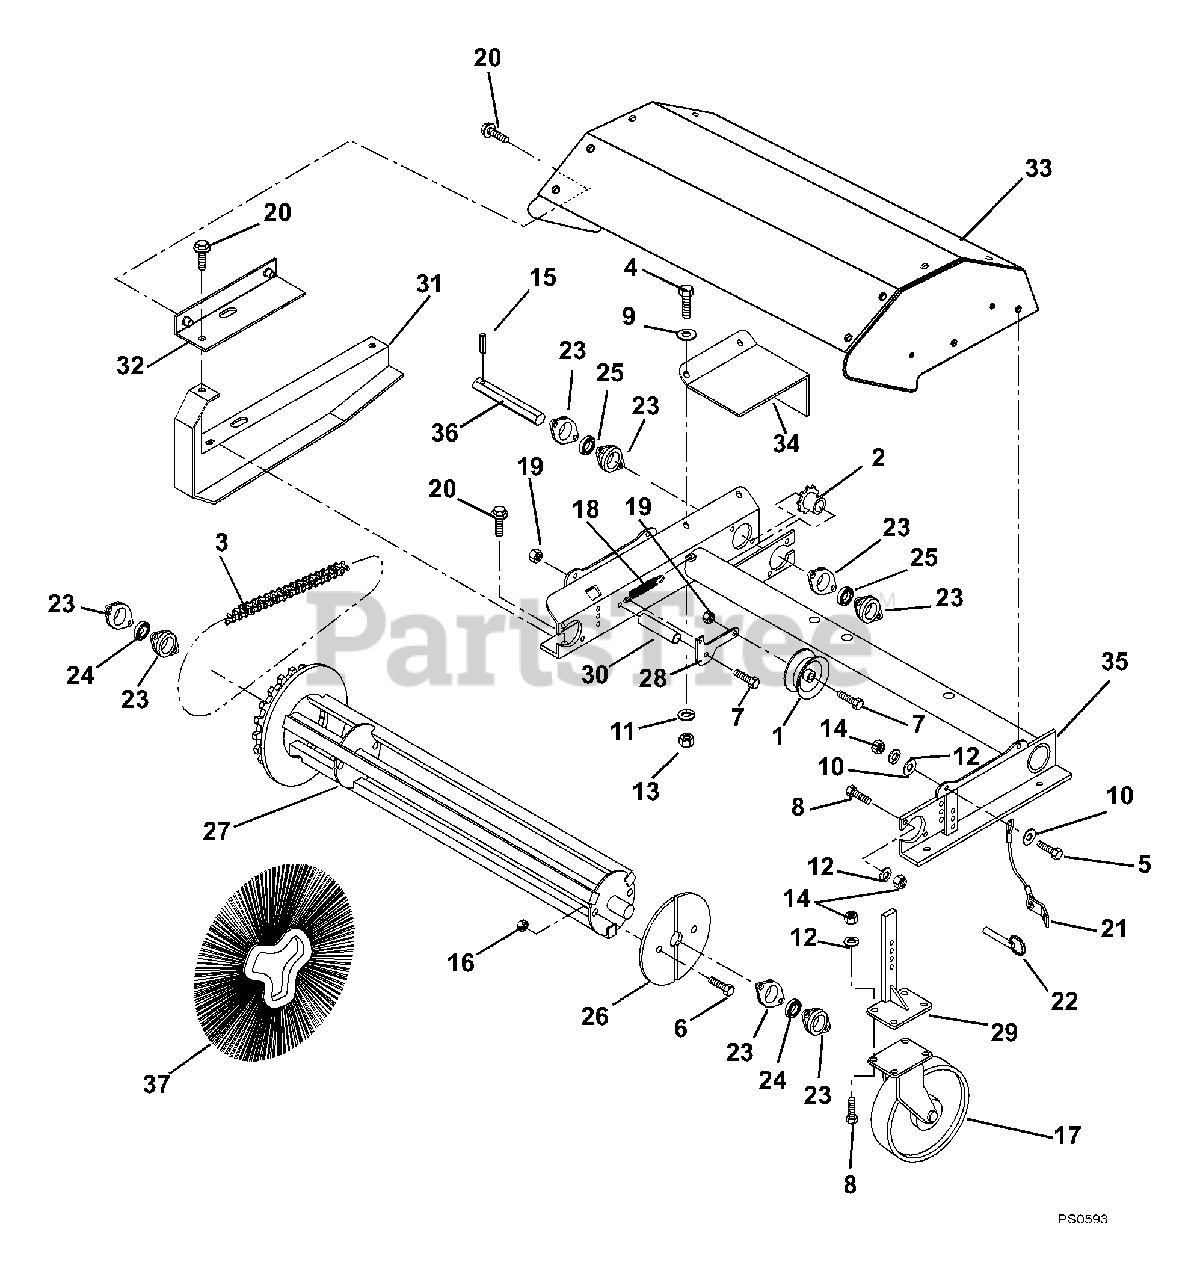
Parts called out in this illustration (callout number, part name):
1	CHAIN TIGHTENER
2	SPROCKET
3	CHAIN, ASS'Y #40X106 EDLS W/LK
4	@BLT-HEX .25-20X.75 GR5 YWZC
5	@BLT-HEX .31-18X1.00 GR5 YWZC
6	@BLT-HEX .31-18X2.25 GR5 YWZC
7	@BLT-HEX .38-16X1.50 GR5 YWZC
8	@BLT-HEX .31-18X.75 GR5 YWZC
9	@WSHR-FL-STL.281X.62X.065 YWZC
10	@WSHR-FL-STL.312X.734X.065 YWZ
11	@WSHR-LK .25X.062 REG YWZC
12	@WSHR-LK .31X.078 REG YWZC
13	@NUT-HEX .25-20 YWZC
14	@NUT-HEX .31-18 YWZC
15	PIN, SPRING LOK .187 X 1.25
16	NUT, LOK STAMPED .312-18 TINN.
17	WHL, 5 DIA.
18	SPRING, TENSION .50 X 3.0
19	@NUT-LK-CTR .38-16 YWZC
20	SCREW, GR 10.9 M6X1-20
21	LANYARD,.06 CAB.1.25X6,TYP C
22	PIN, HITCH, .38 X 2
23	FLANGE, SPHERICAL 2"
24	BRG 1.00 BORE, SPHER. OD.
25	BRG-BALL .884HEXX52MMX1.07
26	RETAINER PLATE (SET OF 2)
27	WELD, CORE C36TW
28	ARM, IDLER,BRM C36TW
29	WELD, CASTER LEG, C36TW
30	BSHG, .62X12 GA X.75
31	SHIELD,CHAIN, ARIENS
32	SHIELD, CHAIN,TOP,ARIENS
33	KIT, HD, ARIENS
34	SHIELD, INPUT, ARIENS
35	WELD, BFRM,ARIENS
36	SHAFT, HEX 20.5, W/HOLE
37	SET,SECTION,24",P,CONV.
